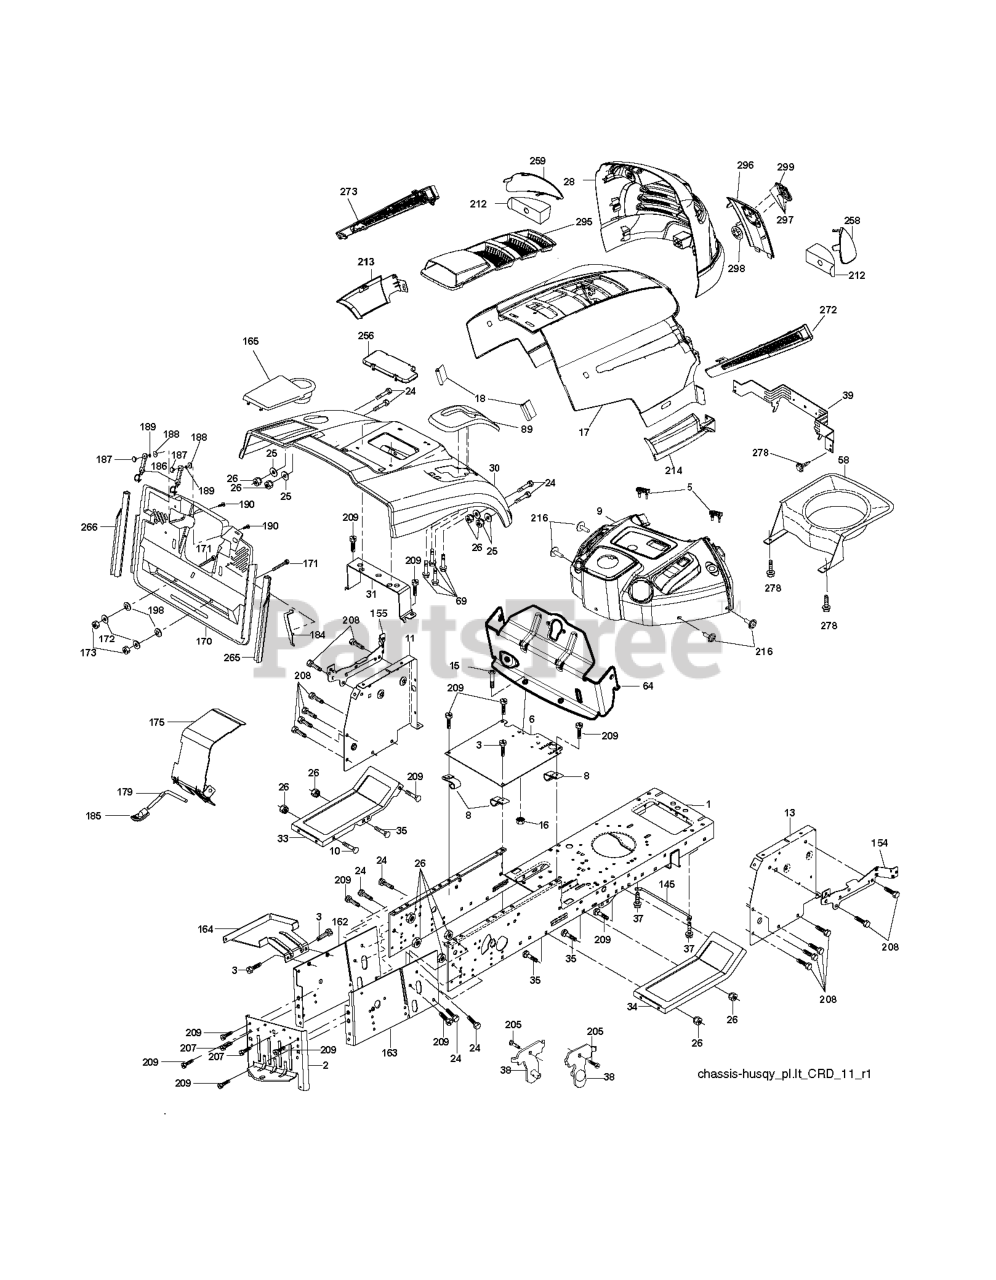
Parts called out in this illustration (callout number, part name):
2	DRAWBAR
3	SCREW 3/8-16X3/4
5	BUMPER DASH
6	PLATE
8	CLIP,INSULATOR
10	BOLT D
11	PANEL.DASH.LH.LTX
13	PANEL ASM, DASH RH
15	Screw, Machine, Truss Head 5/16-18 UNC x 3/4
16	NUT
17	HOOD
18	BUMPER.HOOD.TEX.HUSQVARNA
25	WASHER
26	NUT
28	RP GRILLE/LENS ASM.
30	CONSOLE.CRD.AUTO.GRY
31	BRACKET SUPPORT FENDER
33	FOOTREST PNT LH
34	FOOTREST PNT RH
37	Screw 5/16-18 x 1/2 Hex, Self Tapping 5/16-18 x 1/2
38	BRACKET ASM PIVOT MOWER REAR
39	BRACKET PIVOT
69	SCREW.HI-LO.CONSOLE
89	CONSOLE.CRD.AUTO.GREY.2005
145	ROD.PIVOT.HOOD
162	BRACKET
163	BRACKET EXTEN CHASSIS RH CRD
165	RP.COVER.BATTERY.CRD.GREY
172	WASHER
175	DOOR TRAP
179	ROD PIVOT FBI
184	BRACKET.ACTUATOR.BAGGER.SRD
186	LATCH ASSY
187	WELDNUT
189	LOCKWASHER #10
190	SCREW
207	SCREW, 5/16-18 X 1/2
208	SCREW 3/8-16X1/2
209	SCREW, 3/8-16X3/4
212	INSERT REFLECTIVE
213	SKIRT SIDE LH
214	SKIRT SIDE RH
216	SCREW HEXWSHR 1/4-20X3/4
256	COVER FENDER CRD
258	LENS.HUSQVARNA LT.RH
259	LENS.HUSQVARNA LT.LH
265	SEALING
266	SEALING
272	VENT SIDE HOOD RH
273	VENT SIDE HOOD LH
278	SCREW
295	VENT TOP HOOD
296	TRIM
297	CLIP.RETAINER.TINNER.
298	NUT PUSH M
299	RP LOGO
